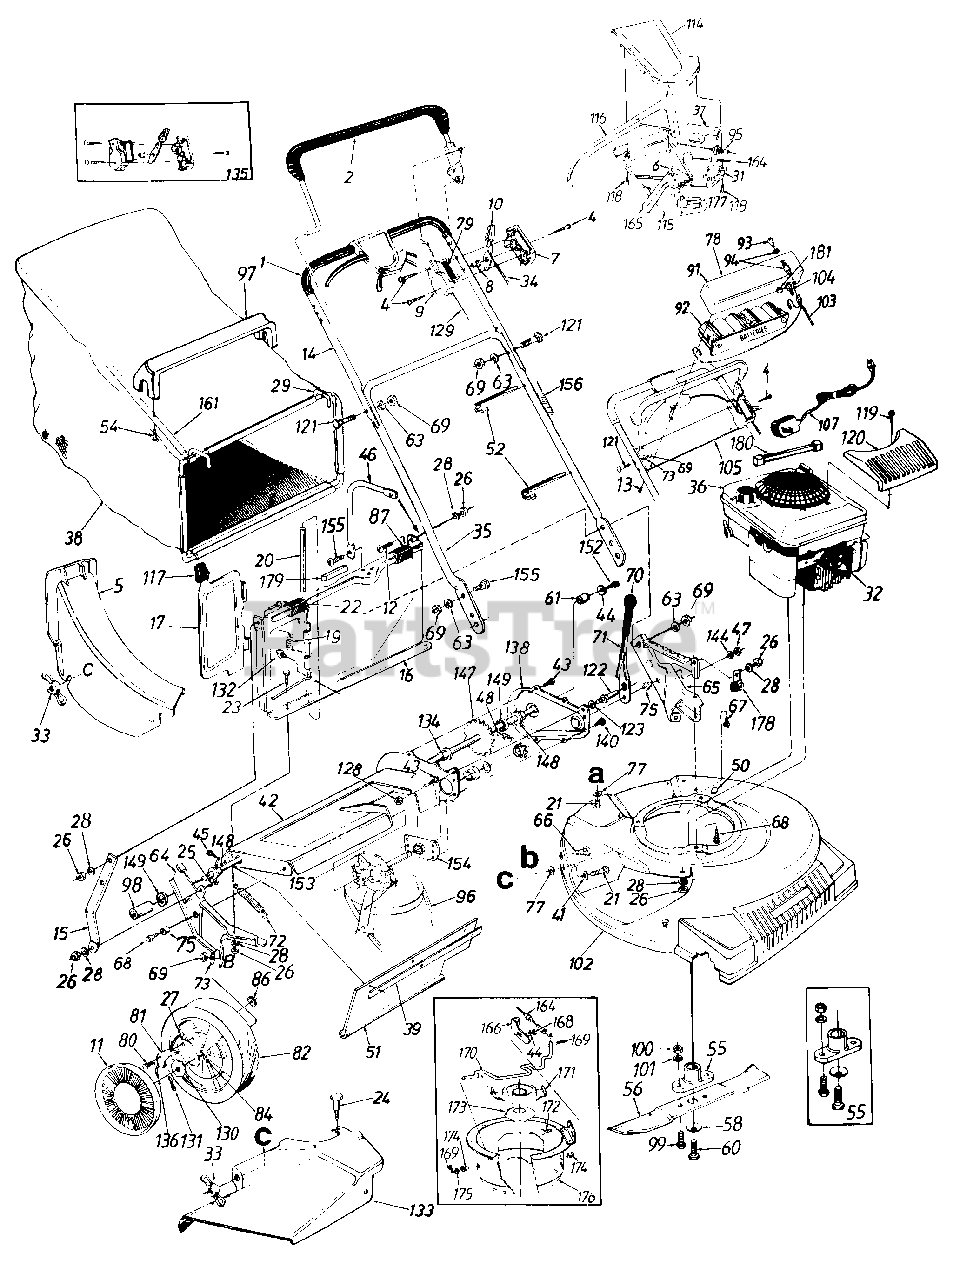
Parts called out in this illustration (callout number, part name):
1	Grip
2	Control Handle Ass'y. L.H.
4	Truss Mach. Scr. #12 x 1.50" Lg.
5	Rear Discharge Chute Ass'y.
6	3 Tooth Rack Gear Insert
7	Control Panel Half
8	Control Disc Pin
9	Clutch Panel Half
10	Throttle Control Lever
11	Hub Cap
12	Truss Mach. Scr. 1/4-20 x .62"t
13	Hex AB-Tap Scr. 1.0" Lg.
20	Pivot Pint
21	Carriage Bolt 1/4-20 x .62"
22	Truss Mach. Scr. 1/4-20 x .75"
23	Hex Bolt 1/4-20 x .5" Lg.
24	Shoulder Bolt Special
25	Hex Bolt 1/4-20 x .62" Lg.
26	Hex Nut 1/4-20 Thd.
27	Pawl Plate
28	L-Wash. 1/4" I.D.
31	S.P. Control Cover
32	Spark Plug Insulator
33	Wing Nut
34	Throttle Control Wire 61"
35	Lower Handle
36	Engine
37	6-Speed Rack Cable Brkt.
38	Grass Bagt
39	Retaining Strip
41	Fl-Wash. .344" I.D. x .62"
44	Bell-Wash. 1/4" I.D.
45	Hex AB-Tap Scr. 1/4 X .62"
46	Catcher Panel Support Armt
47	Hex Patch L-Nut 3/8-24 Thd.
48	#48 Chain .500" Pitch x 30 Links
51	Rear Flap 3.75" x 17.30" Lg.
52	Cable Tie
54	Hex AB-Tap Scr. #12 x 1.25"t
55	Blade Adapter Kit
56	21" Blade
58	Bell-Wash..46" I.D.
60	Hex Bolt 7/16-20 x 1.5"
61	Spacer.513" I.D.
63	L-Wash. 5/16" I.D.
64	R.H. Handle Wheel Brkt. Ass'y.
65	L.H. Handle Wheel Brkt. Ass'y.
66	Carriage Bolt 5/16-18 x .62"
67	Hex B-Tap Scr. 5/16-18
68	Hex TT-Tap Scr. 3/8-16
69	Hex Nut 5/16-18 Thd.
71	Height Adj. Lever
72	Extension Spring 3.80" Lg.
73	Bell-Wash. 5/16" I.D.
75	Shld. Spacer .5" Dia.
77	Bolt Retainer 1/4 x .50" O.D.
78	Instruction Label
79	Control Label
80	Shld. Scr. .342" Dia. x .268
81	Pawl
82	Wheel Ass'y. Comp. Rear
84	Sleeve Bearing 1/2" I.D.
86	Flat Nut 1/4-20 Thd.
87	Panel Clipt
91	Upper Battery Tray
92	12 Volt Battery
94	Key Switch
95	S.P. Cable 50" Lg.
96	"V"-Belt
97	Bag Handlet
98	Sleeve.526" I.D.
99	Hex Bolt 3/8-24 x 1.0" Lg.
100	Hex Nut 3/8-24 Thd.
101	L-Wash. 3/8" I.D.
104	Plug
105	Lower Battery Tray
107	Battery Charger
114	Self-Propelled Control Cover
115	Self-Propelled Control Cover
116	Control Lever
117	Door Gript
118	Fl-"C"-Sunk Hd. Tap Scr. #10 x .75" Lg.
119	Truss Hd. AB-Tap Scr. #6 x .62" Lg.
120	Engine Cover
121	Curved Carr. Bolt 5/16-18 x 1.38" Lg.
122	Shld. Pin 1.43" Lg.
123	L-Wash. 3/8" I.D.
128	Hex Jam Nut 3/8-24 Thd.
129	Control Cable 46"
130	Ratchet Wheel 1.62" O.D.
131	Cotter Pin 118" Dia. x 1"
132	Hex B-Tap Scr. #10 x .38" Lg.
133	Side Chute Deflector Ass'y.
134	Hex Flange Bearing
135	Kit Control Housing Comp.
136	Spring Nylon
144	Fl-Wash. .385" I.D. x 87"
147	Rear Shaft Ass'y. 21.94" Lg.
148	Hex Flange Brg. .506" I.D.
149	Fl-Wash. .531" I.D. x .930"
152	Hex Bolt 1/4-20 x .62" Lg. (Grade 5)
153	Transmission Comp.
155	Truss Mach. Scr. 5/16-18 x .75" Lg.
156	Plastic Tubing
164	Spd. Control Cable 50" Lg.
165	6-Spd. Shift Lever
169	Cot-Pin 3/32" Dia. x .75" Lg.
170	Shift Rod
171	Movable Pulley Half Ass'y.
172	Carr. Bolt 1/4-20 x .5 Lg.
173	Splined Pulley Half
174	Flanged Bushing
175	Fl-Wash. .328" I.D. x .68" O.D.
176	Cable Mtg. Brkt. Ass'y.
177	Shift Lever Spring
178	Clamp
179	Foam Stript
180	Ext. Harness
181	Fuse Holder
